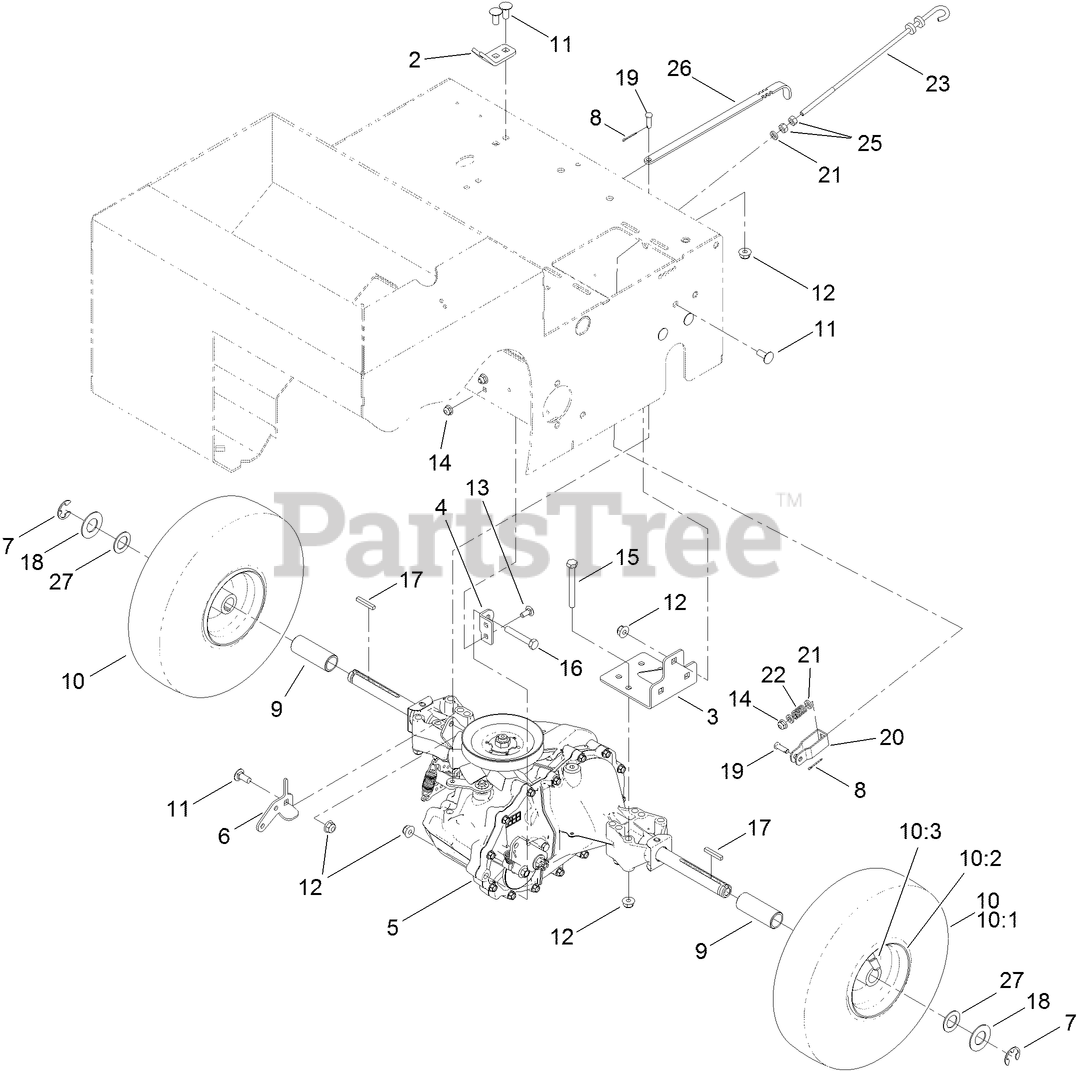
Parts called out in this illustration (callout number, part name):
2	BRACKET-CABLE
3	BRACKET-AXLE
4	BRACKET-TRANSAXLE, TORQUE
5	TRANSAXLE ASM
6	BRACKET-TRANSAXLE
7	E-RING
8	PIN-COTTER
9	SPACER
10	WHEEL ASM
10:2	WHEEL-RIM
10:3	VALVE
11	SCREW-CARR
12	NUT-HF, NI
13	SCREW-CARR
14	NUT-HF
15	SCREW-HH
16	SCREW-HH
17	KEY-SQUARE
18	WASHER-FLAT
19	PIN-CLEVIS
20	CLEVIS
21	SPACER-PLATE, PIVOT
22	SPRING-COMPRESSION
23	ROD-BRAKE
25	NUT-HEX
26	LEVER-BYPASS
27	WASHER
